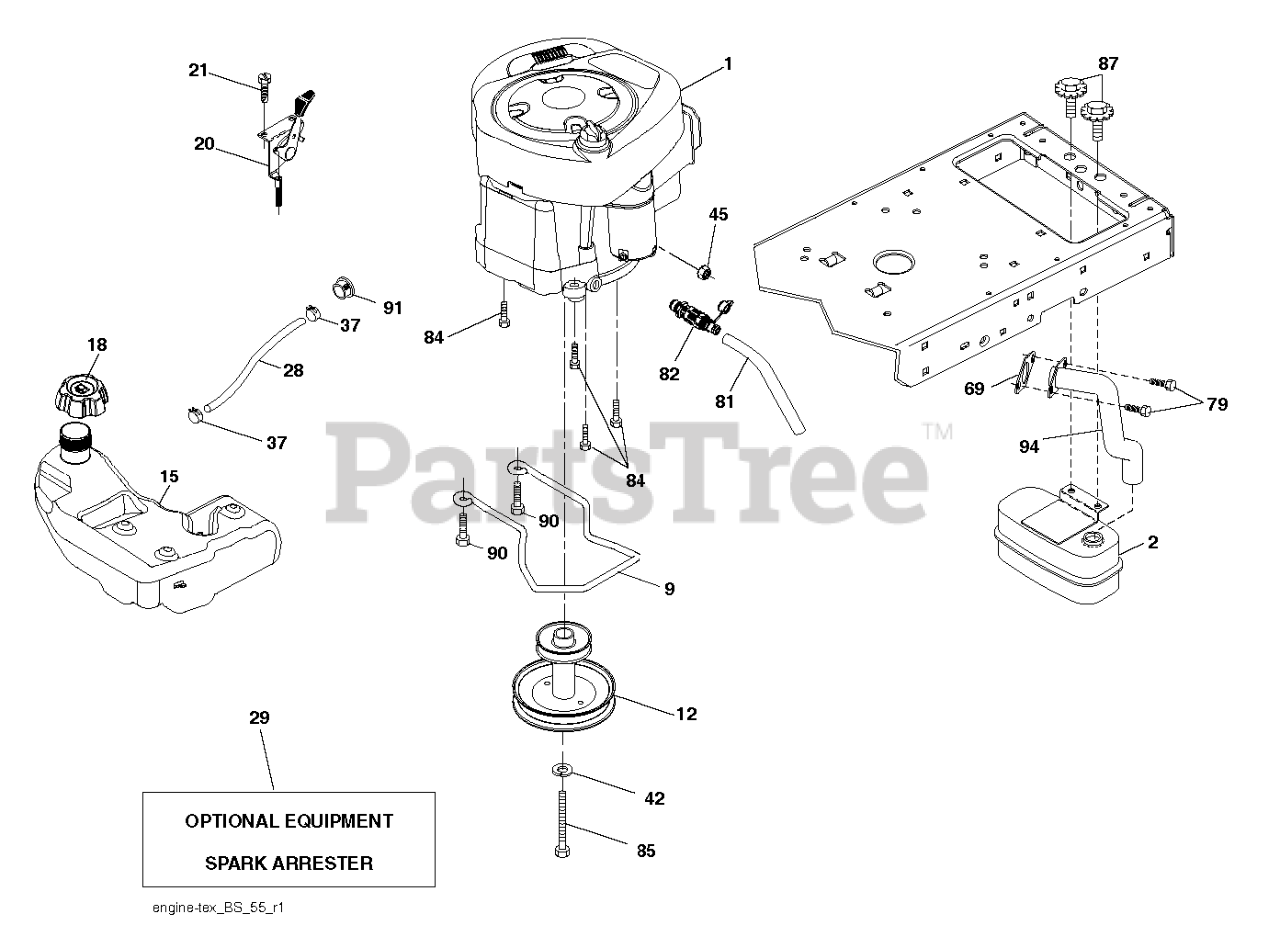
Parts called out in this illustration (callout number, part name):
2	MUFFLER.ASM.SINGLE
9	KEEPER.BELT.ENG.4.25"2.BLT.431
12	ENGINE.PULLEY
15	Tanks
18	CAP ASSY FUEL 3" GRAY
18	FUEL CAP
20	THROTTLE.COBRA.21".RSTART.BLK
28	LINE.FUEL.64"REAR.EMIS
29	KIT.SPARK ARRESTOR 794945 B&S
37	HOSE CLAMP
69	REPL BY 532 27 22-93
81	TUBE, DRAIN OIL ASM.
82	VALUE.OIL.DRAIN
84	SCREW.3/8-16
85	BOLT.HEX.7/16-20X4.GR5.1.5BLUE
87	BOLT.5/16-18UNCX3/4 W/SEMS.BLK
90	SCREW 3/8-16X1
91	BUSHING.1.375OD
94	EXHAUST.TUBE.B&S.28/31
